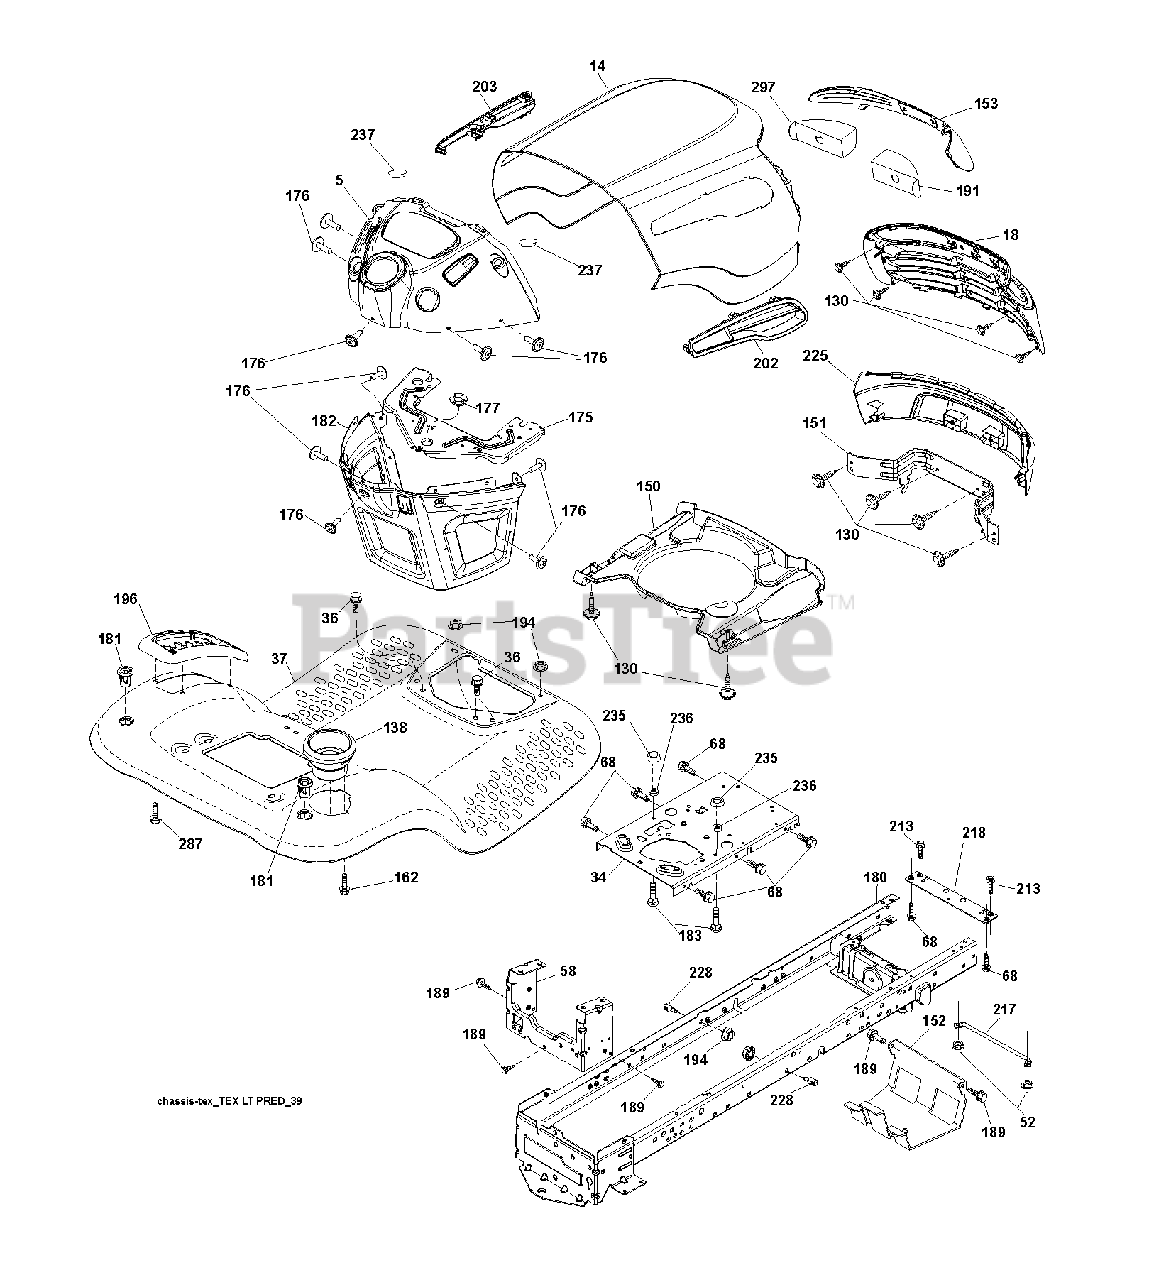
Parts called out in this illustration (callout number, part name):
34	PLATE.ENGINE.WELDED.CHASSIS
36	SCREW 5/16"
52	LOCKNUT
58	DRAWBAR UPPER 2PC SMALL FENDER
130	SCREW.#10 X 0.750.BOS THREAD
138	CUPHOLDER.TL.TEX.BLACK
151	BRACKET.PIVOT.ALPHA.LT
152	SHIELD BROWNING
153	LENS.PREDATOR.LT
162	SCREW.HI-LO.CONSOLE
175	CROSSMEMBER
176	SCREW.#10-24X5/8.RN.QU
177	BUSHING STEERING
181	FEND/FTRST.PCH.CPH.NFW
182	DASH.LWER.PREDATOR/HUSQ.LT
183	BOLT.5/16-18X1-1/4 FULL THD
189	SCREW
191	INSERT.REFLECT.PREDATOR.LT.RH
194	NUT LOCK HEX FLANGE 5/16-18
196	CONSOLE.ASM.DECKLFT.BL/RBT.TLT
213	BOLT
217	ROD.PIVOT.HOOD
218	X-PIECE.HOOD.STOP.NON/
228	STUD.FASTNER.W/ANTI-ROTATE
235	SPACER FENDER
236	NUT.CENTERLOCK.5/16-
237	PLUG.MOUNT.CARGO.BLK
297	REFLECTOR.INSERT.PRED.LH.LT
